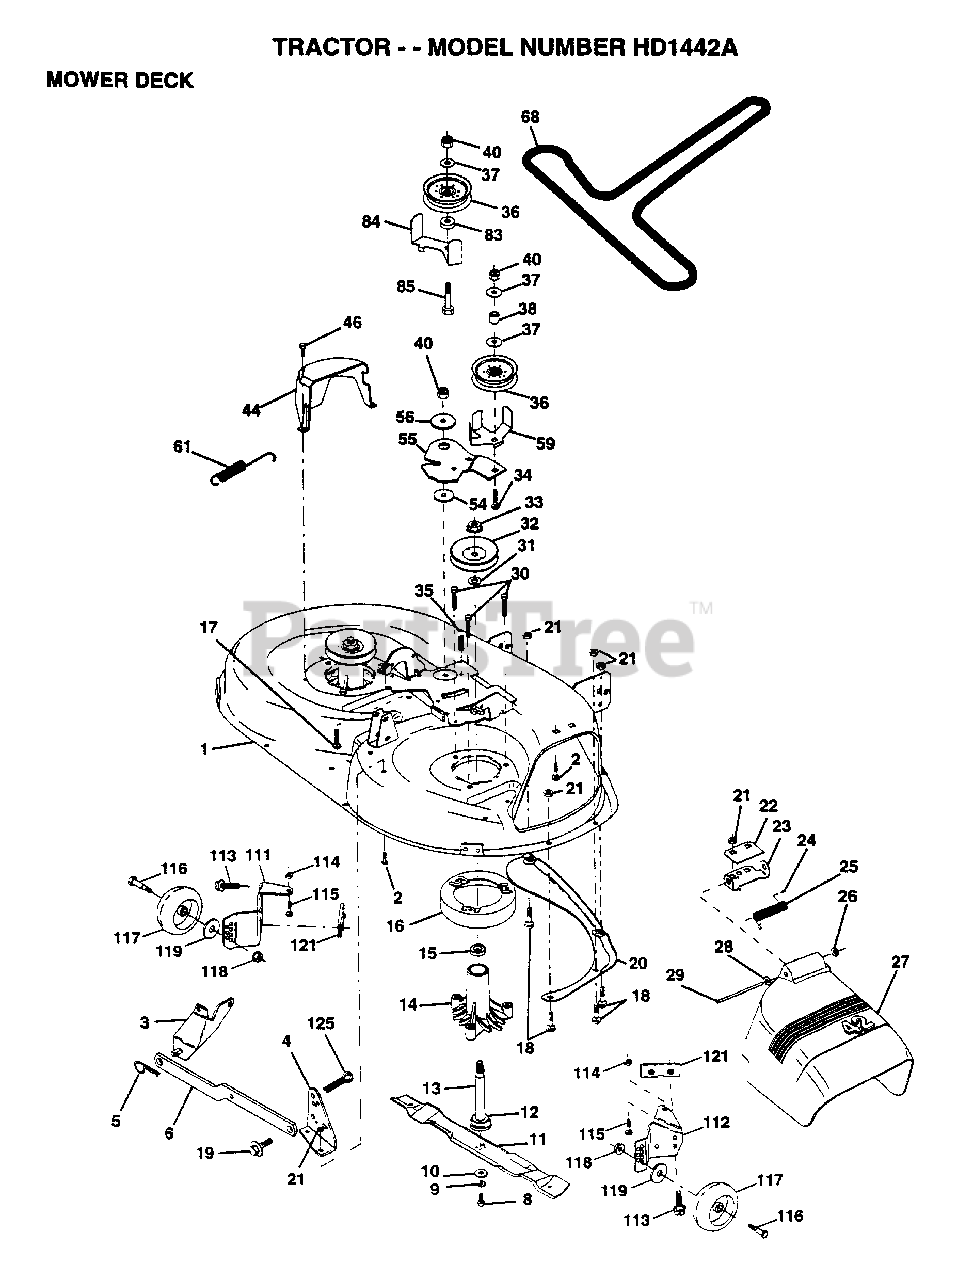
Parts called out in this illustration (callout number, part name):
1	DECK.WELD.42.
2	BOLT
3	BRKT ASM SWAY BAR
4	BRKT DECK SW BAR
8	BLADE BOLT
10	WASHER.HARD.BLADE
11	"BLADE.42"" HIPERF"
12	BEARING.BALL
14	HSG ASM MANDREL
15	BEARING
16	STRIPPER RND MWR
17	BOLT CARRIAGE
18	BOLT
19	BOLT SHD 5/16-18
22	STIFFENER BRKT
23	DEFLECTOR BRKT
24	CAP-SLEEVE LT
25	SPRING TORSION
26	NUT PUSH M
27	DEFLECTOR.SHIELD
28	WASHER
29	HINGE ROD
31	WASHER
34	BOLT
35	XMAS TREE FASTNER
36	FLAT IDLER PULLEY
37	WASHER
44	GUARD MAND LH BLK
46	SCREW.1/4-20X5/8
54	HARDENED WASHER
56	SPACER RETAINER
59	GUARD IDLER TUV
61	SPRING.EXTENSION
68	BELT.V.T-PATH
83	WASHER
85	BOLT
113	SCREW
116	BOLT.SHOULDER
117	WHEEL.GUAGE.MED.
118	LOCKNUT
119	WASHER
121	BRACKET.EXTRD.GWL
125	COTTER PIN
